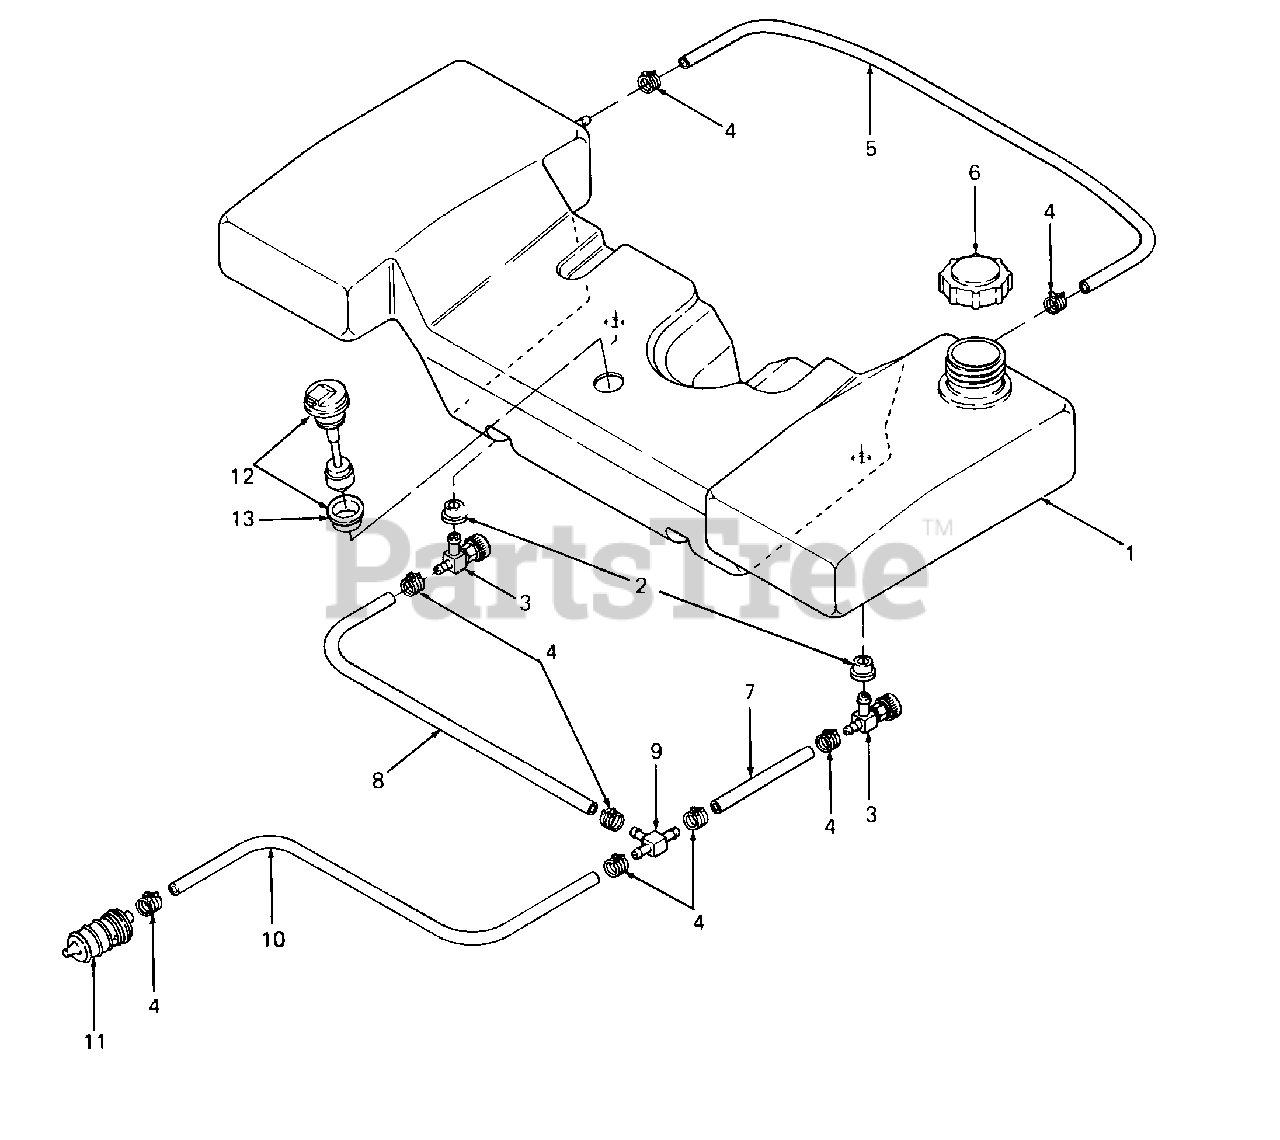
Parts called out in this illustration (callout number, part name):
1	Tank, Fuel
2	Bushing
3	Valve, Fuel Shutoff
4	Clamp, Hose
5	Line, Fuel - 24" Lg
6	Cap, Fuel
7	Line, Fuel - 5" Lg
8	Line, Fuel - 19" Lg
9	T-Fitting
10	Line, Fuel - 38" Lg
11	Filter, Fuel
12	Sensor, Low Fuel
13	Bushing, Rubber
